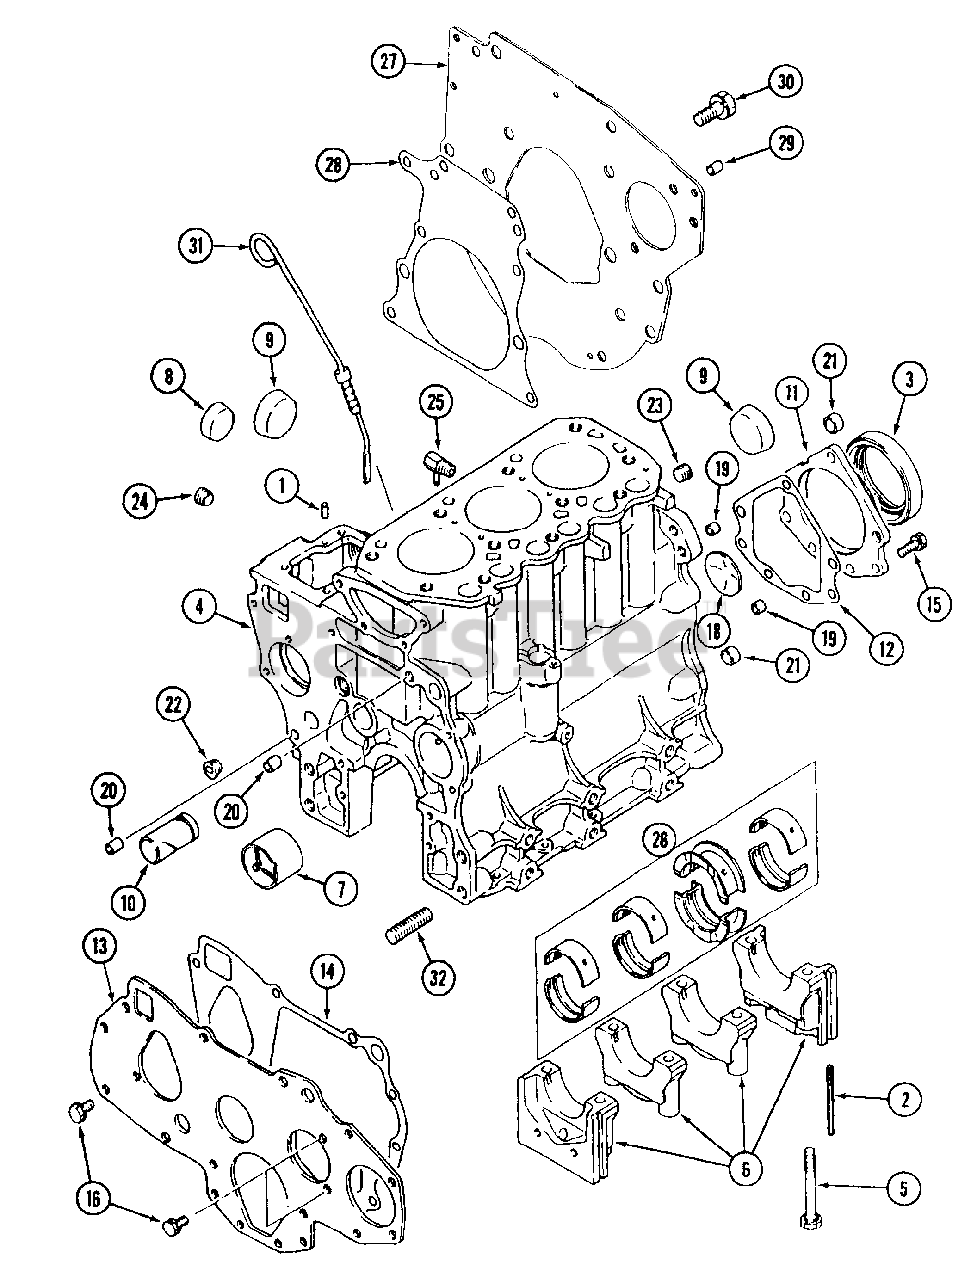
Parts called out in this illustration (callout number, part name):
2	Seal, Slide
4	Block Sub Ass'y., Cylinder
5	Bolt, Bearing Cap
6	Cap Ass'y., Bearing
8	Cap, Sealing
9	Cap, Sealing
10	Shaft, Idler
11	Case, Oil Seal
12	Gasket, Oil Seal
13	Plate, Frame
14	Gasket, Front Plate
15	Bolt, w/Washer
16	Bolt, w/Washer
18	Plug, Expansion
20	Bushing, Knock
21	Bushing, Knock
22	Plug, Taper
23	Plug, Taper
24	Plug, Taper
26	Bearing Set, Crankshaft
27	Plate, Rear
28	Gasket, Rear Plate
30	Bolt, w/Washer
31	Gauge, Oil Level
